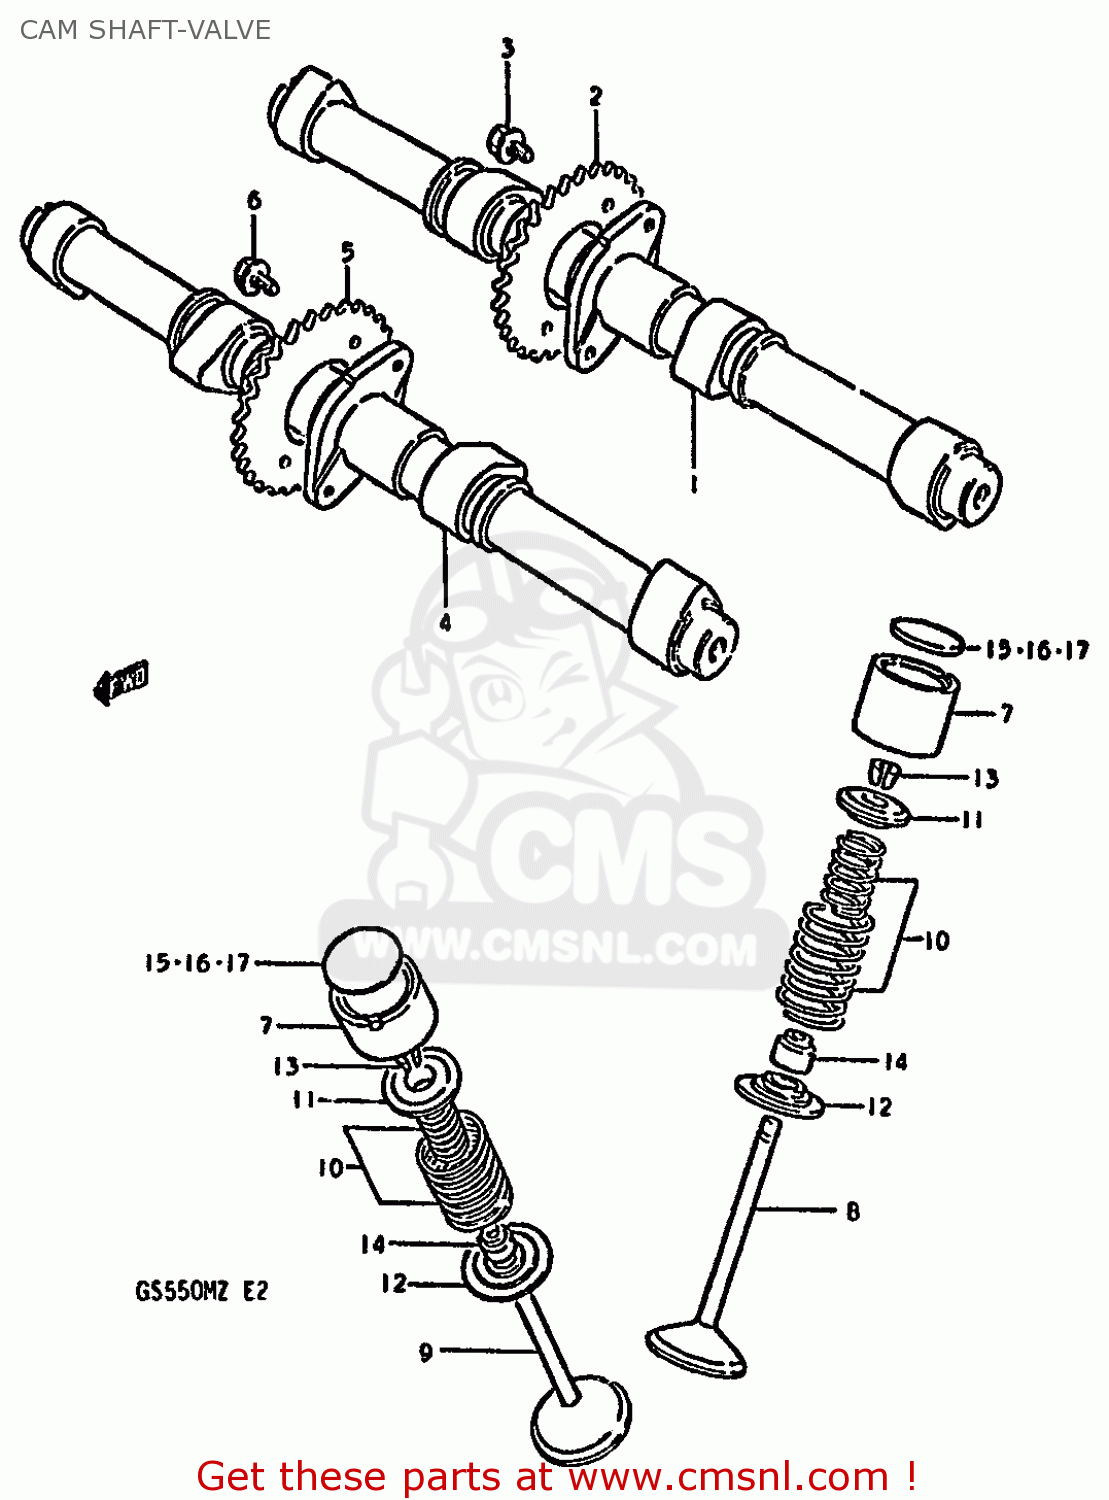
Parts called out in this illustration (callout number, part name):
1	CAMSHAFT,INTAKE
2	SPROCKET,INTAKE CAMSHAFT
3	BOLT(7X11)
4	CAMSHAFT,EXHAUST
5	SPROCKET,EXHAUST CAMSHAFT
6	BOLT(7X11)
7	TAPPET
8	VALVE,INTAKE
9	VALVE,EXHAUST
10	SPRING SET,VALVE
11	RETAINER,VALVE SPRING
12	SEAT,VALVE SPRING
13	COTTER VALVE
14	SEAL,OIL(7X14.4X9)
15	SHIM,TAPPET
16	SHIM,TAPPET
17	SHIM,TAPPET
